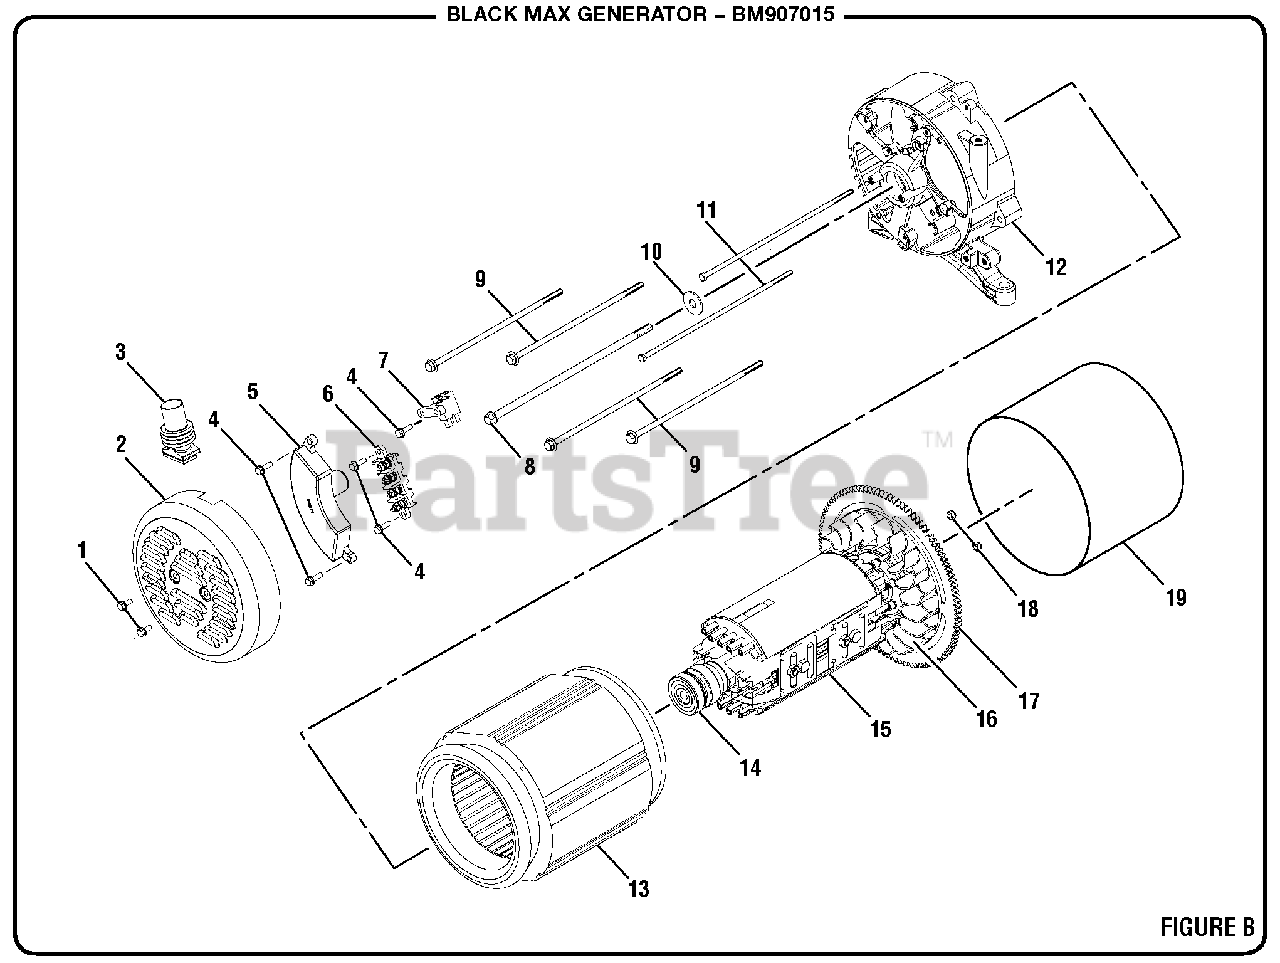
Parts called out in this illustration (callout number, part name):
1	Bolt (M5 x 12 mm, Hex Hd.)
2	Brush Cover
3	Rubber Boot
4	Bolt (M5 x 16 mm, Hex Hd.)
5	Automatic Voltage Regulator
6	Terminal Block
7	Brush Assembly
8	Bolt (5/16-24 x 235 mm, Hex Washer Hd.)
9	Bolt (M6 x 188 mm, Hex Washer Hd.)
10	Washer (ID10 x OD28 x 3t)
11	Bolt (M5 x 210 mm, Hex Washer Hd.)
12	Bearing Housing
13	Stator Assembly
14	Ball Bearing
15	Rotor Assembly
17	Starter Gear
18	Hex Nut (M5)
19	Generator Head Cover
